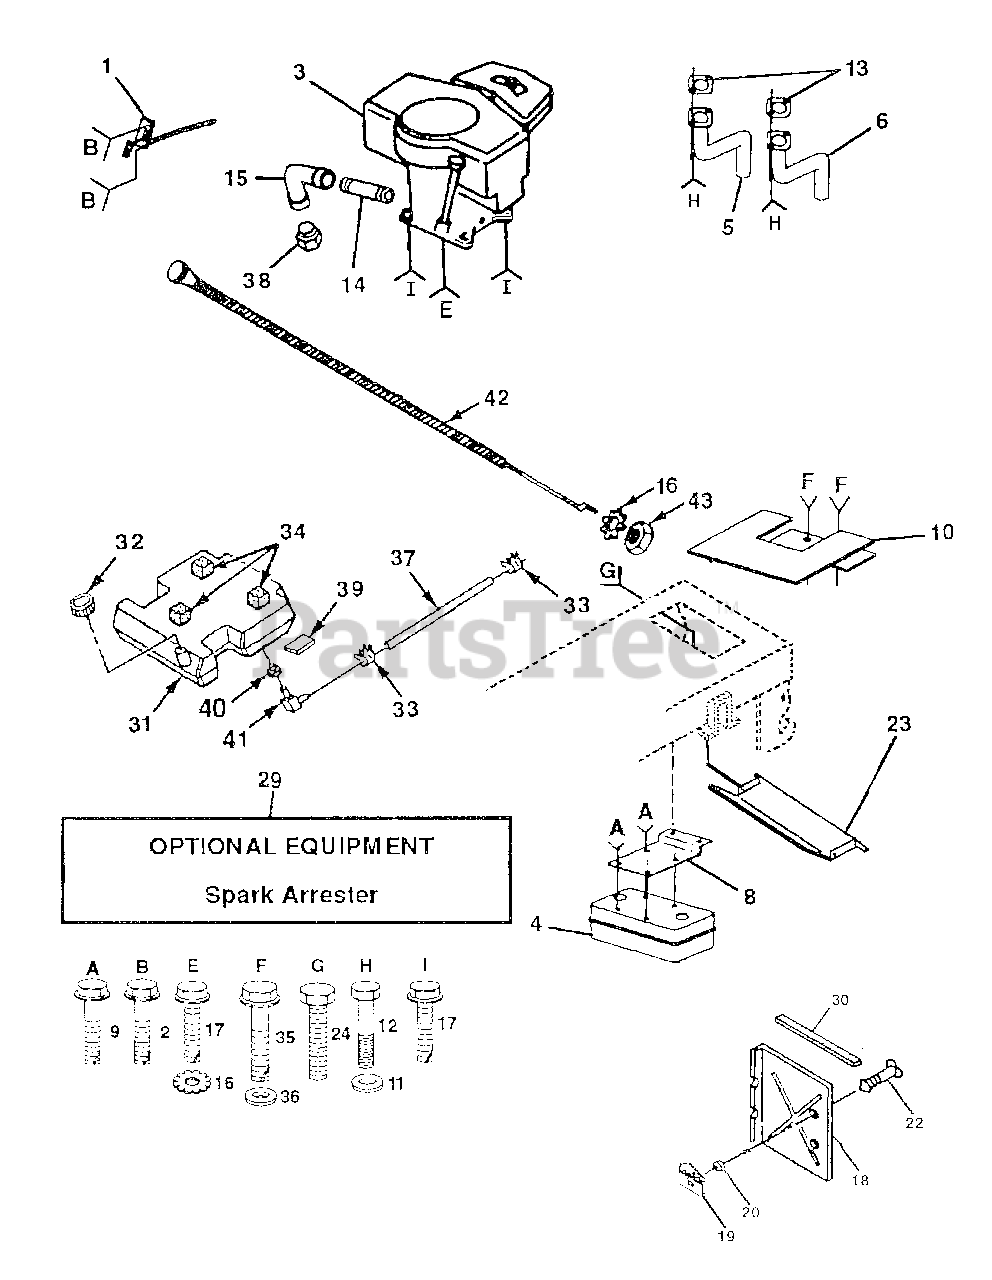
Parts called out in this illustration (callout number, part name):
1	Control RH Blk Flg 37 88
2	Screw Hex Thd Cut 1/4-20x5/8 T
4	Muffler VGT YT Dual Inlet
5	Tube Manifold LH
6	Tube Manifold RH
8	Bracket Muffler Mounting
9	Screw Hex Wsh Thd Cut 1/4-20
10	Shield Heat LT
11	Washer Lock Hvy Spr 5/16-18
12	Screw Hex Skt 5/16-18 unc x 3/4
13	Muffler Gasket
14	Nipple Pipe 3/8 Npt X 4-1/2"
15	Elbow Std 90 Degree 3/8-18 Npt
16	Washer Lock Ext Tooth 3/8
17	Screw Thdrol 3/8-16 x 1-1/2
18	Shield Heat Electric
19	Receptacle 1/4 Turn
20	Retainer 1/4 Turn
22	Stud 1/4 Turn
23	Shield Heat Browning LT/YT
24	Screw Tap Hex #10-24unc X 1/2
29	Kit Spark Arrestor (Flat Scrn)
30	Foam Strip 18"
31	Tank Fuel 3 50 Rear
32	Cap Asm Fuel
33	Clamp Hose Blk
34	Pad, Spacer
35	Screw Thdrol 5/16-18 x 3/4
36	Washer 13/32 x 1 x 14 Ga.
37	Line Fuel 54"
38	Plug Oil Drain
39	Pad, Idler
40	Bushing
41	Stem Tank Fuel
42	Choke Control
43	Nut, Fin Hex 3/8-24 Unf
